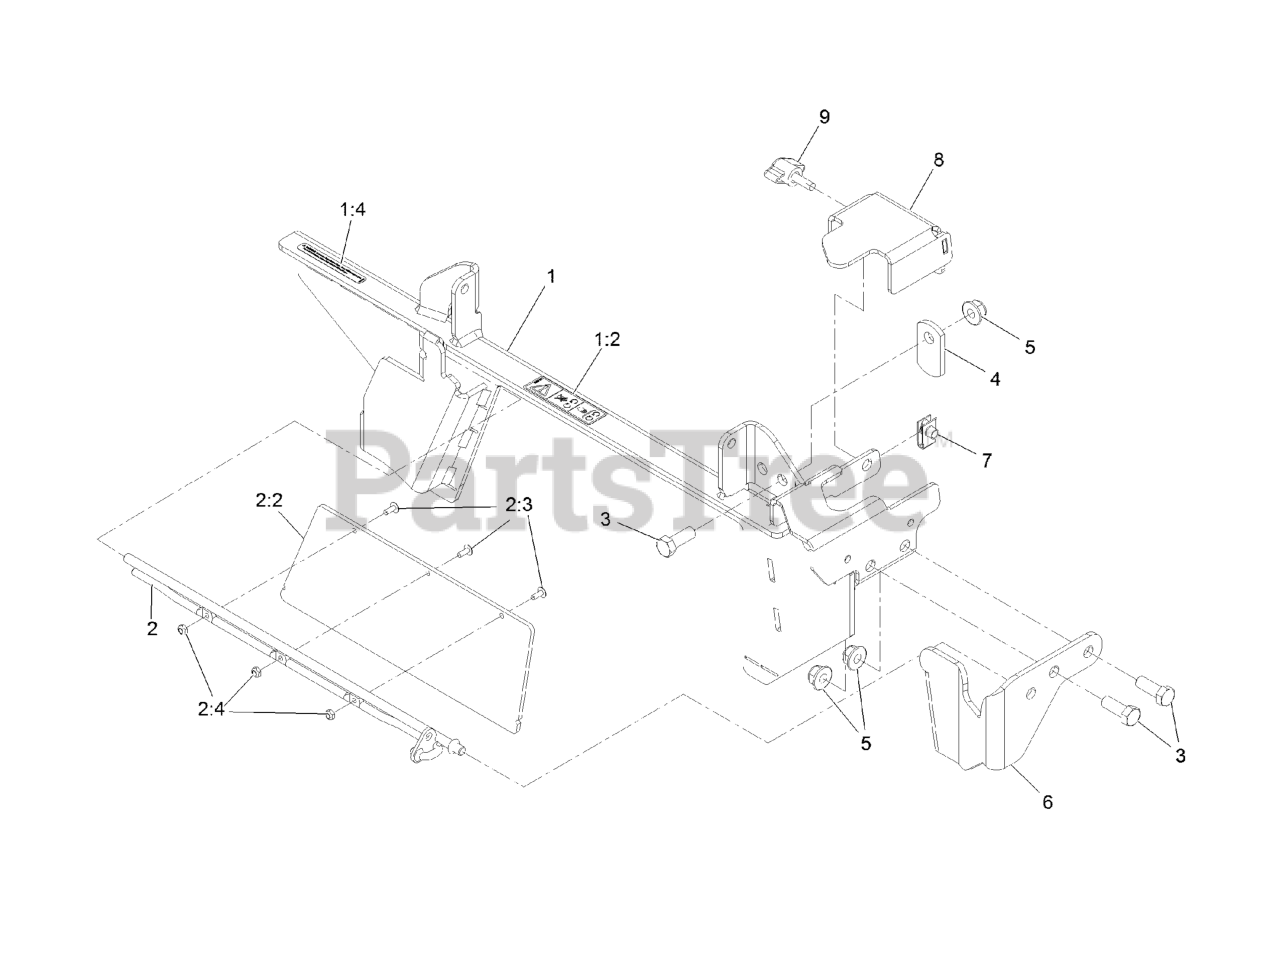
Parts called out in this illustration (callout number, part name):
1	OCD FRAME ASM W/ DECALS
1:2	DECAL, COVER MISSING
1:4	DECAL-WARNING
2	OCD GATE ASM
2:2	GATE-OCD
2:3	SCREW-PTH
2:4	NUT-LOCK, NI
3	SCREW-HH
4	LATCH-CATCHER, GRASS
5	NUT-HF, NI
6	BRKT,CHUTE FRONT
8	BRACKET, CABLE MOUNT
